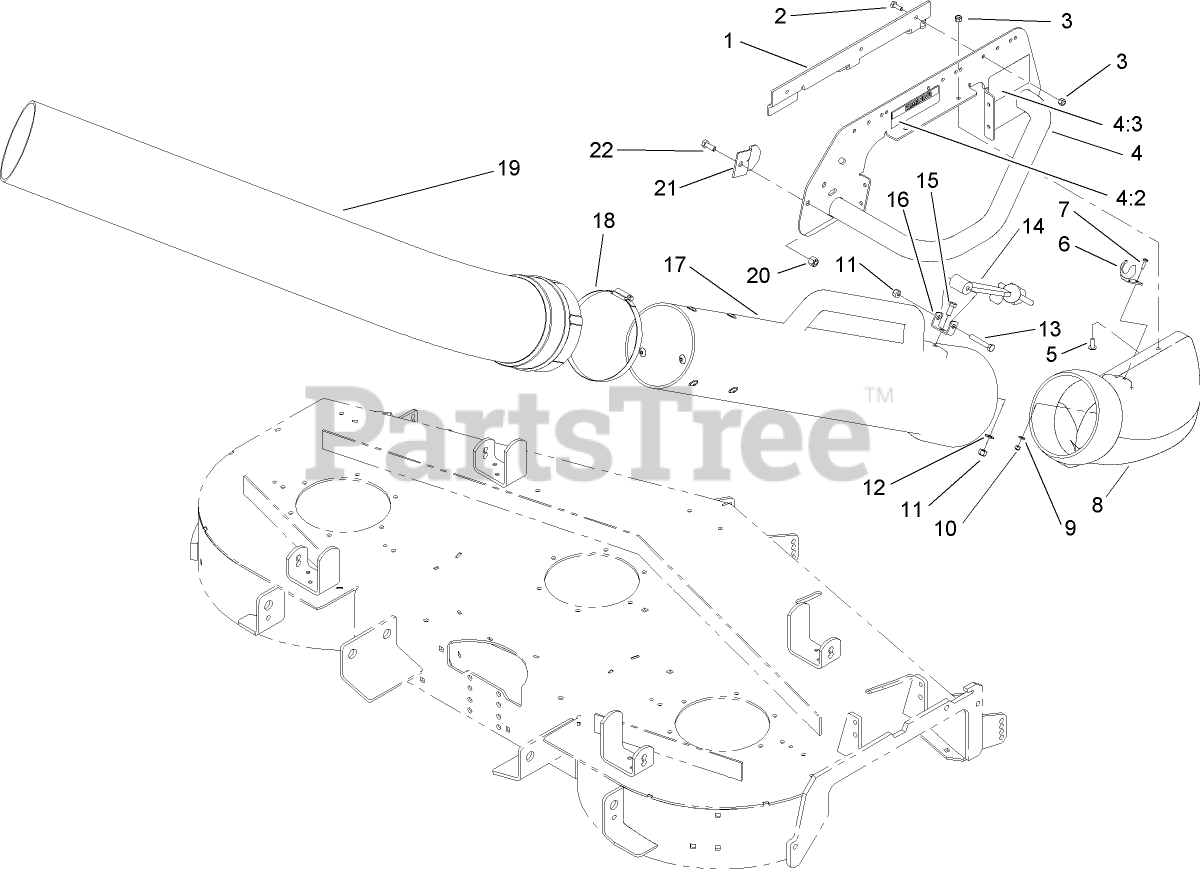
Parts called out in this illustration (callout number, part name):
1	BRACKET-MOUNTING
2	SCREW-HH
3	NUT-LOCK, NI
4	MOUTING PLATE ASM
4:2	DECAL-WARNING
4:3	DECAL-WARNING
5	SCREW-HEAD, TRUSS
6	BRACKET-HOOD
7	SCREW-PPH
9	WASHER-FLAT
10	NUT-LOCK, NI
11	NUT-LOCK, NI
12	WASHER-PLAIN
13	SCREW-HH
14	HOLDDOWN-HOOD
15	SCREW-HH
16	BRACKET-ANCHOR
17	TUBE-STRAIGHT
18	CLAMP-HOSE
19	TUBE-ELBOW
20	NUT-LOCK, NI
21	Bracket-Clamp
22	SCREW-HH
